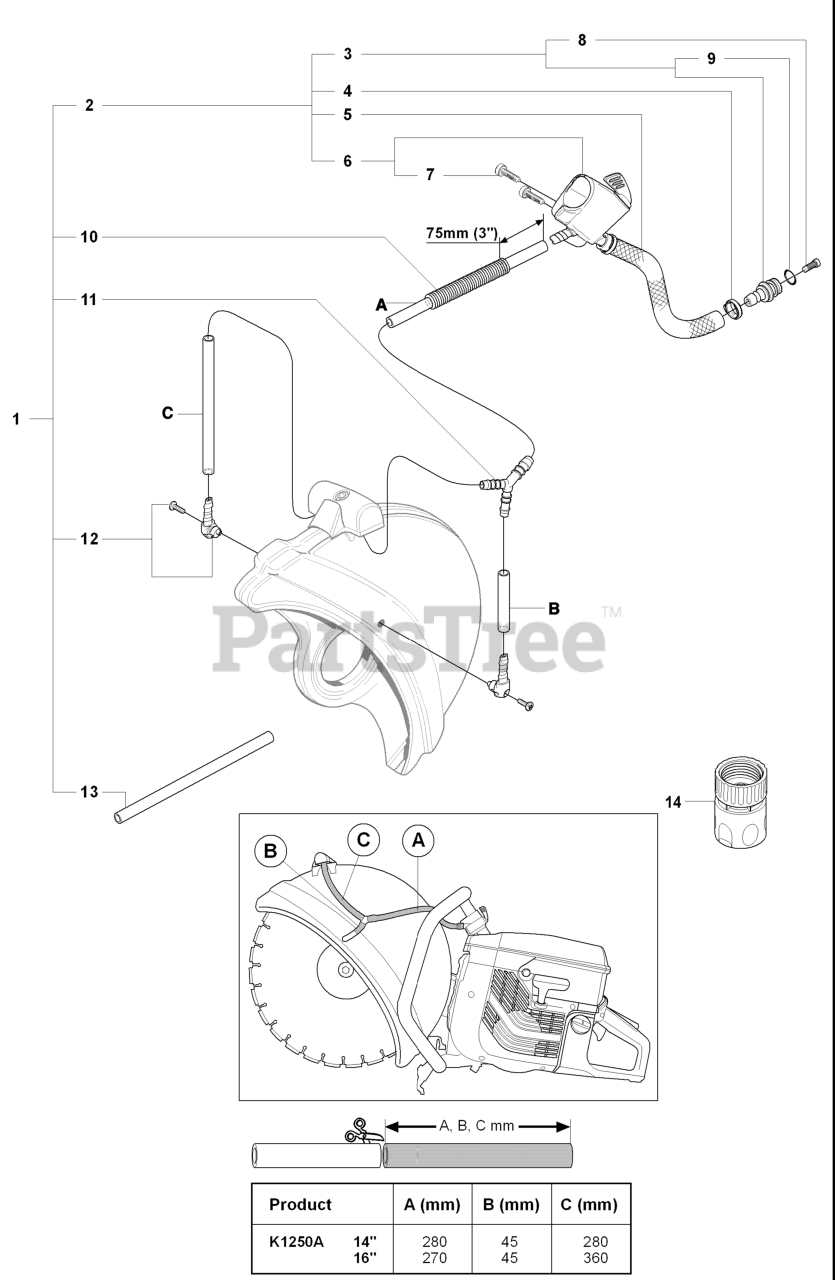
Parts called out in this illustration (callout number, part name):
1	WATER HOSE KIT
2	HOSE
3	NIPPLE
4	CLAMP
5	%HOSE
6	VALVE COMPLETE
7	SCREW
8	FILTER
9	RP O-RING
13	RP HOSE 800MM
14	FEMALE QUICK COUPLER
